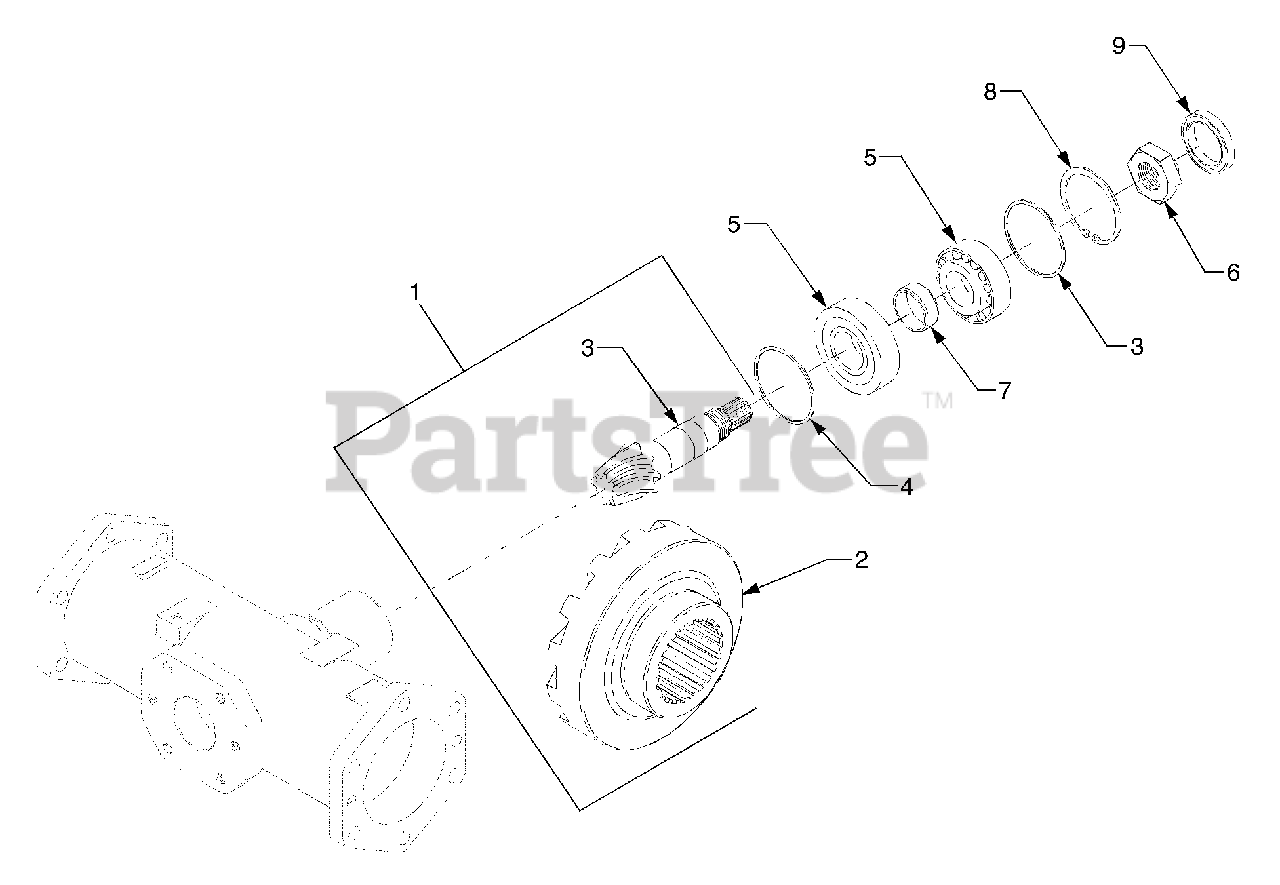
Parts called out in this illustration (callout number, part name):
1	Spiral Bevel Gear Ass'y
2	Gear, 23 Spiral Bevel
3	Shaft, 9 Bevel Pinion
4	Collar (T 5.8)
5	Bearing, Taper Roller
